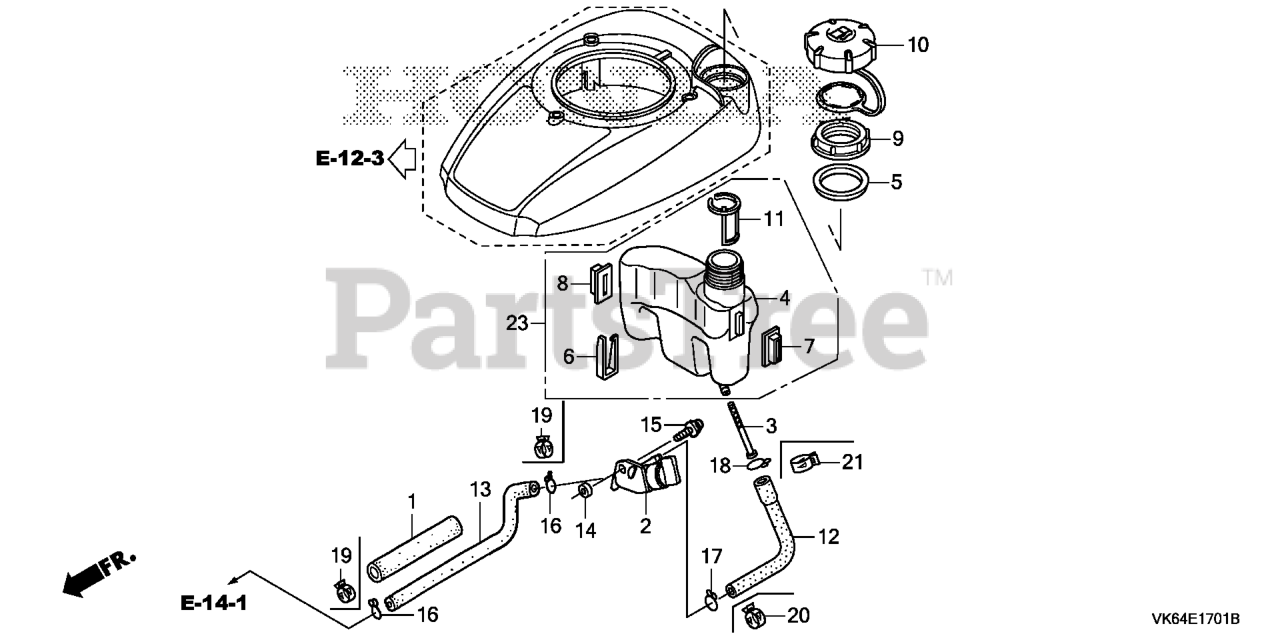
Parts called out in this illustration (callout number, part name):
1	RUBBER, SUPPORTER (107MM)
2	PETCOCK ASSY.
3	FILTER, FUEL
4	TANK, FUEL
5	SEAL, FUEL FILLER NECK
6	CLIP, TANK MOUNTING
7	RUBBER A, TANK MOUNTING
8	RUBBER B, TANK MOUNTING
9	NUT, TANK MOUNTING
10	CAP ASSY., FUEL TANK
11	GAUGE, FUEL LEVEL
12	TUBE, FUEL TANK
13	TUBE, FUEL
13	TUBE, FUEL (FKM)
14	COLLAR, FUEL PETCOCK
15	SCREW-WASHER (5X10)
16	CLIP, TUBE (B8)
17	CLIP, TUBE (B10)
18	CLIP, TUBE (C11)
19	CLIP, TUBE (D8)
20	CLAMP, TUBE (D10)
21	CLAMP, TUBE (D12)
23	TANK KIT, FUEL
